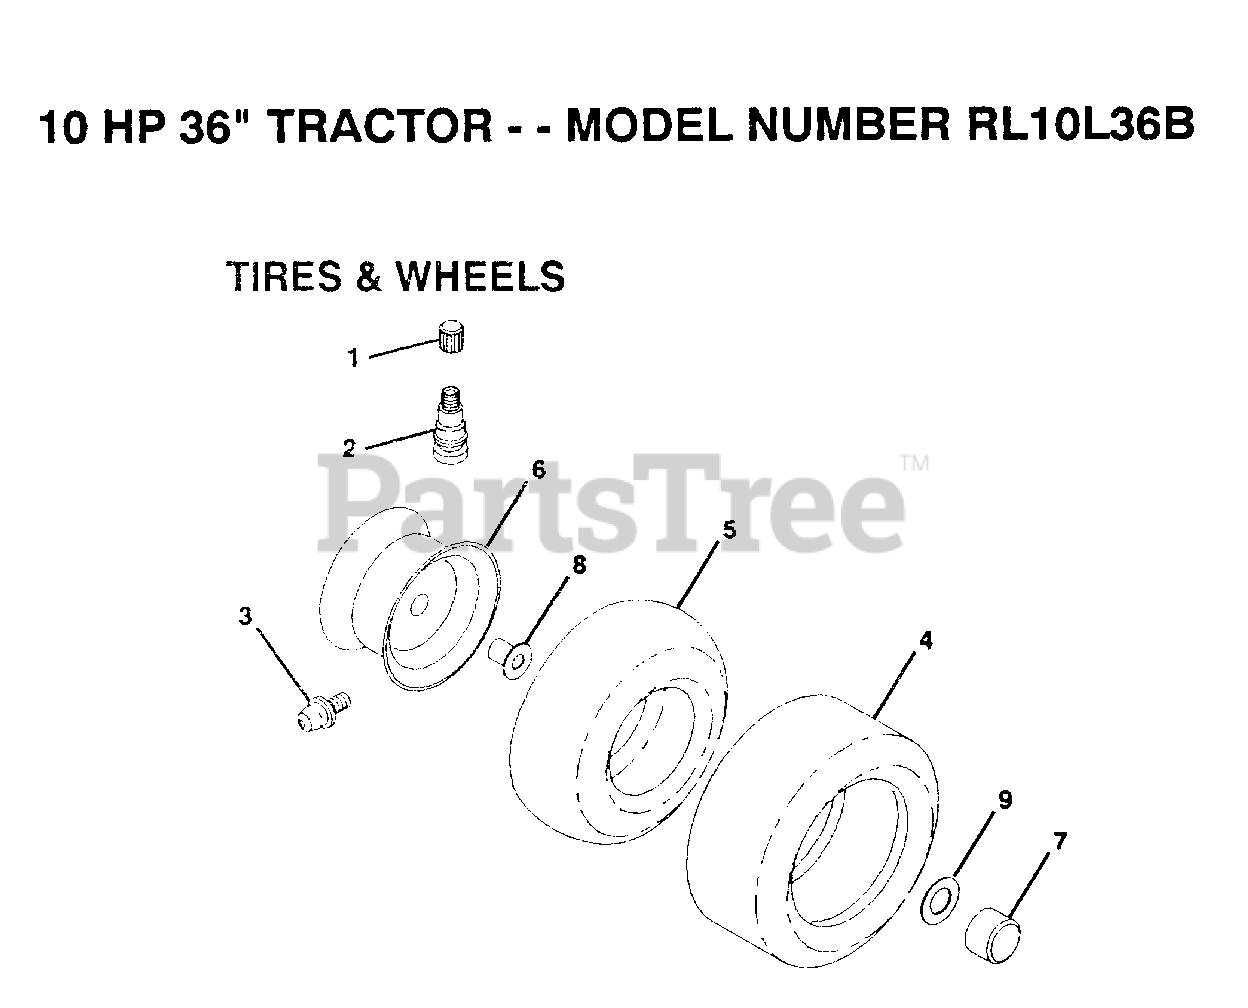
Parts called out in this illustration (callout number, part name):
1	VALVE CAP
2	VALVE STEM LT
3	FITTING LT
5	TUBE.5.3/4.5/6
5	TUBE.16X6.5/7.5-8
7	HUB CAP
8	"FLANGE, BEARING"
9	WASHER
